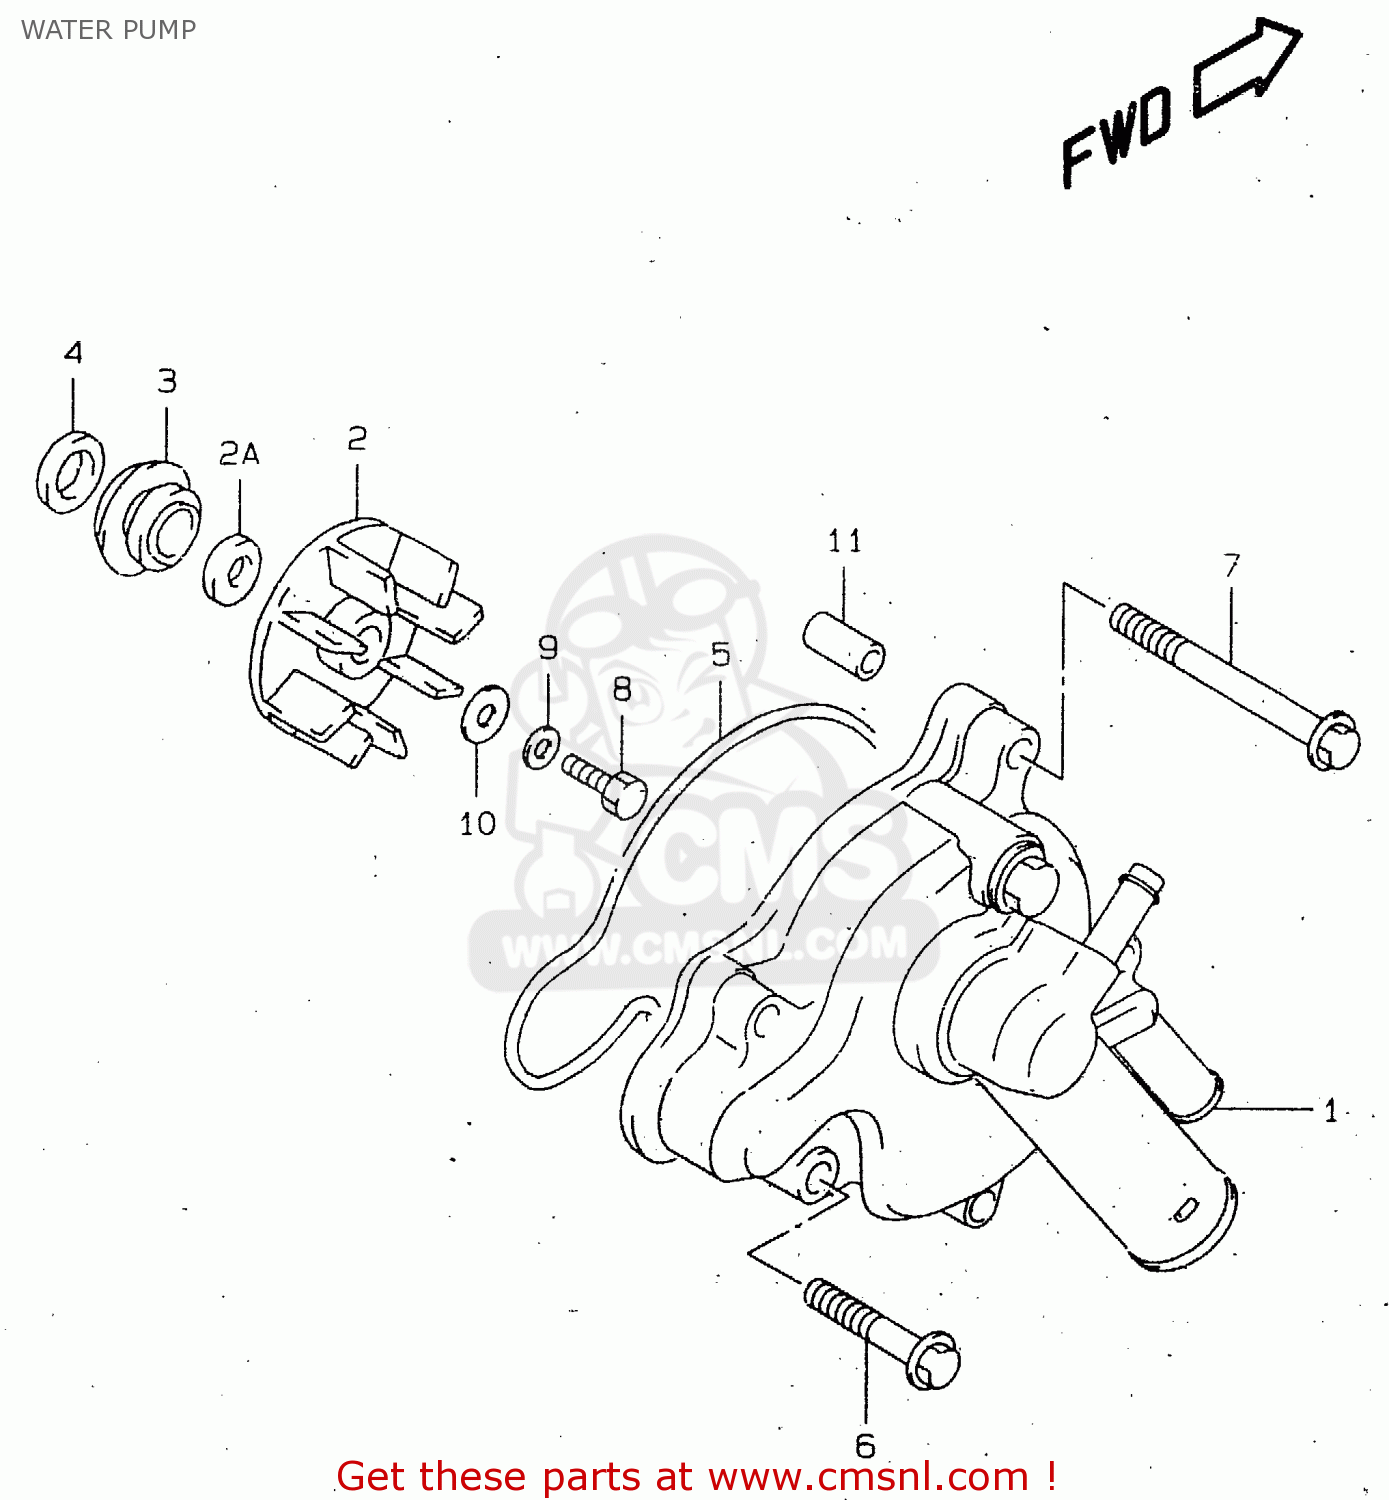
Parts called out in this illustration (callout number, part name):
1	CASE,WATER PUMP
2	IMPELLER,WATER PUMP
2A	WASHER,IMPELLER
3	SEAL,MECHANICAL
4	SEAL,WATER PUMP SHAFT OIL
5	O RING,WATER PUMP CASE
6	BOLT
7	BOLT
8	BOLT(6X13)
9	WASHER
10	GASKET(6X15X2.2) (NAS)
11	PIN
